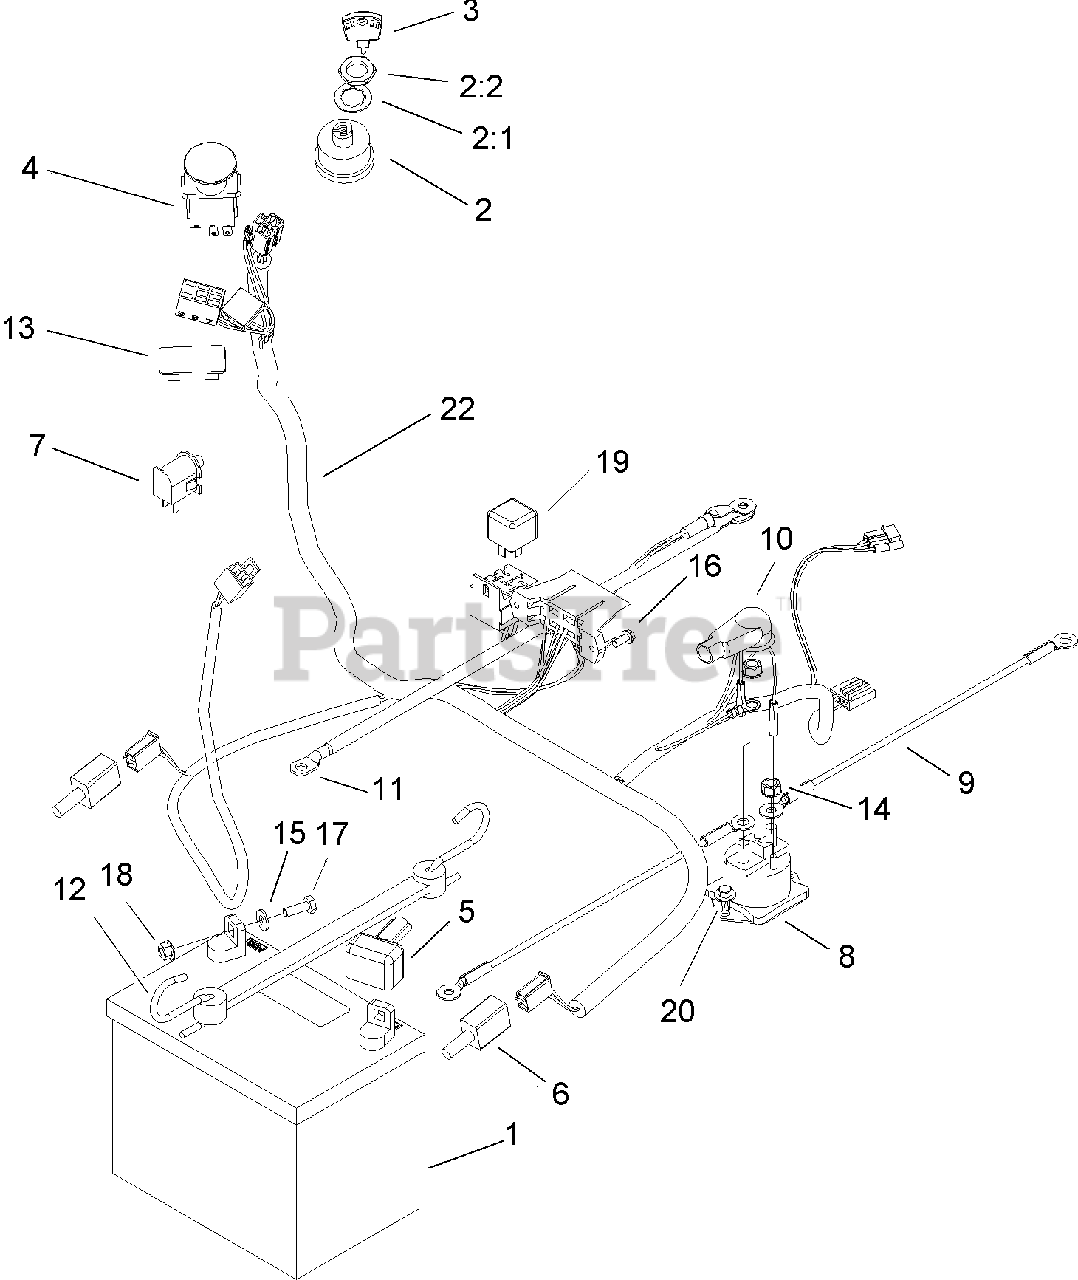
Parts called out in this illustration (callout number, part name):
1	BATTERY-DRY
2	Key Switch ASM
2:1	WASHER-TOOTH
4	SWITCH-PTO
5	BOOT-TERMINAL
7	SWITCH-BAIL
9	WIRE ASM
10	BOOT-INSULATOR, TERMINAL
12	HOLDDOWN-BATTERY
13	PLUG-HOLE
14	NUT-KEPS
15	WASHER-FLAT
16	SCREW-TAPTITE
17	SCREW-HH
20	SCREW-HHF
22	HARNESS-WIRING
